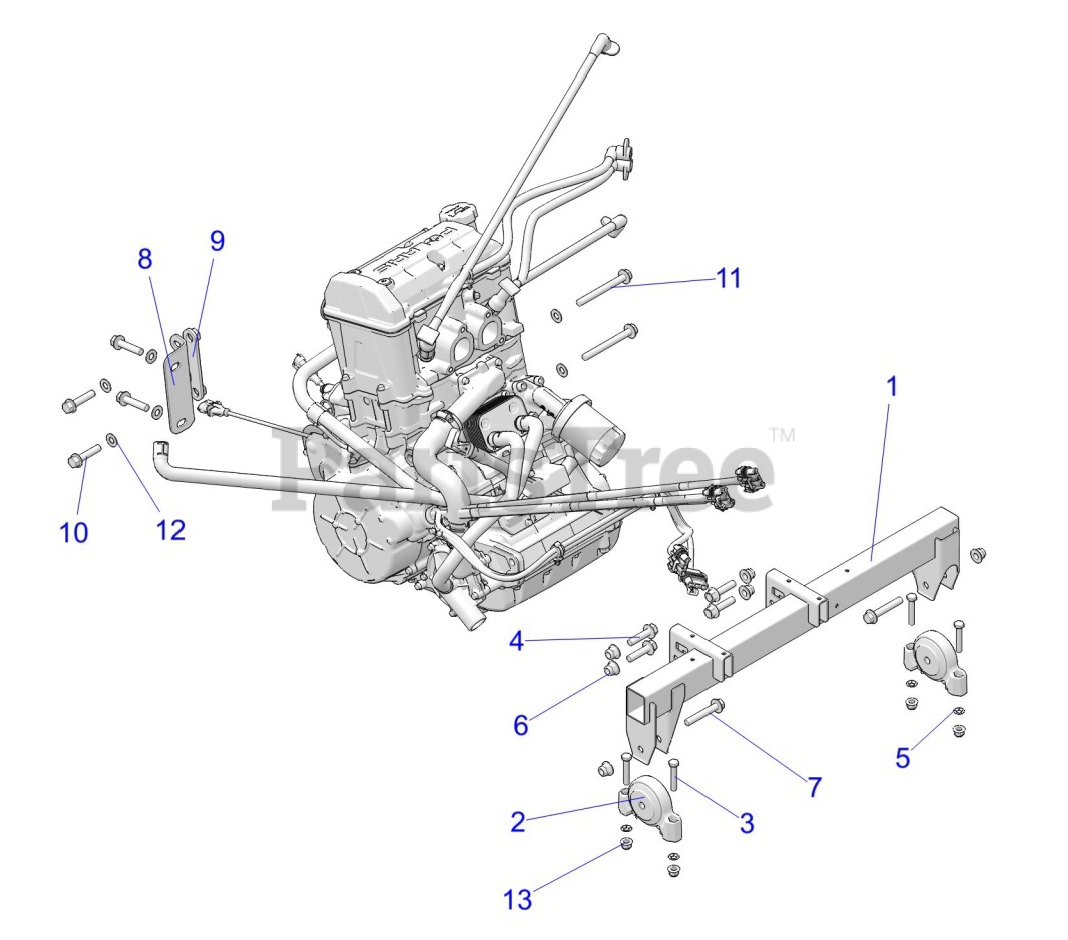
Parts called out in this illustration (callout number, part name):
1	WELD-MOUNT,ENGINE,BLK
2	MOUNT-ISOLATOR,DRIVELINE
3	SCR-HH M8X1.25X45 8.8 ZOD
4	SCR-HXFL-M10X1.25X40 8.8 ZOD
6	NUT-M10X1.25,FLG,NYLOC-OLIVE D
7	BOLT-M10X1.25X60,HXFLG-OLIVE D
8	BRKT-COUPLER,TRANS
9	WELD-NUT,PLATE
10	SCR-HXFL-M10X1.25X45 8.8 ZOD
11	SCR-HXFL-M10X1.25X95 10.9 ZOD
12	WASHER,3/8 FW
13	NUT-M8X1.25,FLG,NYLOC-OLIVE D
